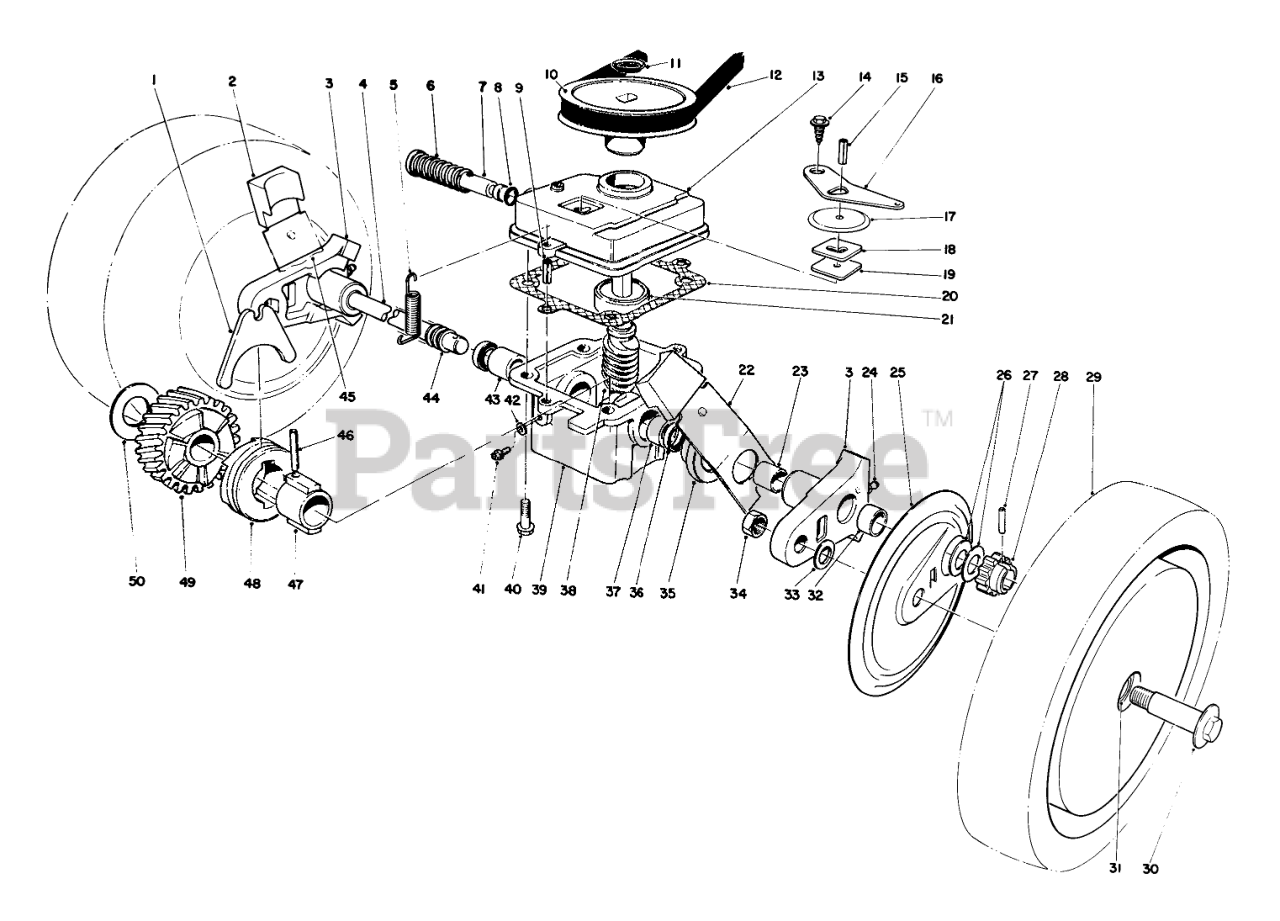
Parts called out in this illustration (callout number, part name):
1	SHIFTER FORK
2	KNOB-ARM
3	Pivot Arm (Incl. Ref. #23, 24 & 32)
4	DRIVE SHAFT (SERVCE)
5	TENSION SPRING
6	SPRING
7	SHIFTER ROD
8	O-RING
9	3/16 X 1/2 ROLL PIN
10	PULLEY
11	PUSH-ON 93-3236
12	V BELT
13	GEAR CASE COVER
14	Screw
15	SPIROL PIN H D
16	SHIFTER ARM
17	DUST COVER
18	LATCH PLATE
19	DUST FILTER
20	GASKET
21	BEARING
22	SPRING ARM ASM SP LH
23	BUSHING
24	FITTING-GREASE
25	WHEEL COVER
26	THRUST WASHER
27	Pin
28	PINION GEAR 14T
29	Wheel, Tire & Gear Assembly (Incl. Ref. #31)
30	WHEEL BOLT
31	BUSHING
32	BUSHING
33	WASHER
34	Nut
35	CAP-END
36	SEAL-OIL
37	BUSHING
38	Worm Shaft & Gear (Incl. Ref. #49)
39	Gear Case (Incl. Ref. #36-37 & 43)
40	Screw
41	NYLON SCREW
42	FILL PLUG GASKET
43	BUSHING
44	COVER-SHAFT, DRIVE
45	SPRING ARM ASM SP RH
46	COIL PIN
47	SLEEVE
48	CLUTCH JAW
49	Helical Gear
50	THRUST WASHER
